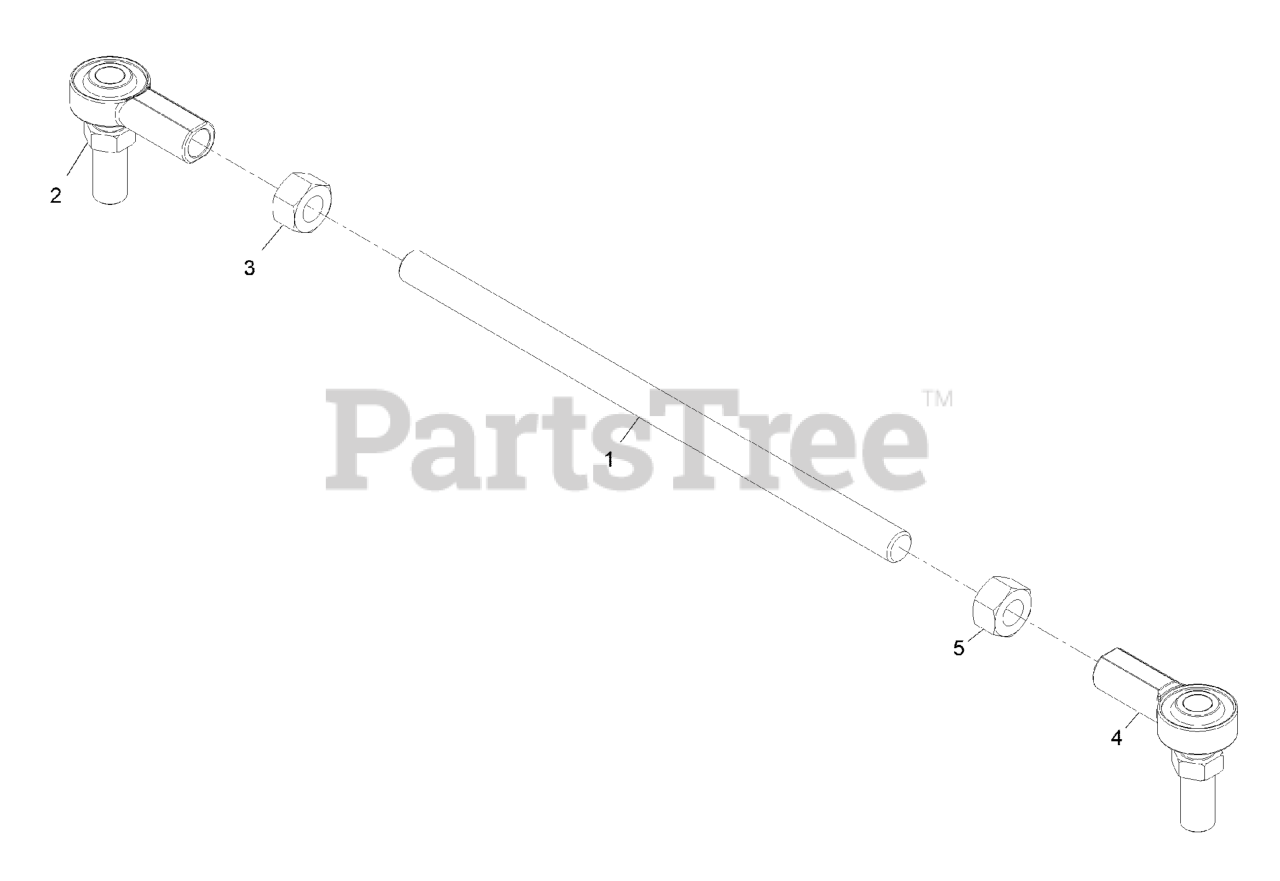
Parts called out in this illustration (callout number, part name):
2	ROD-END, RH
3	NUT-HEX
4	ROD-END, LH
5	NUT-HEX, LH
